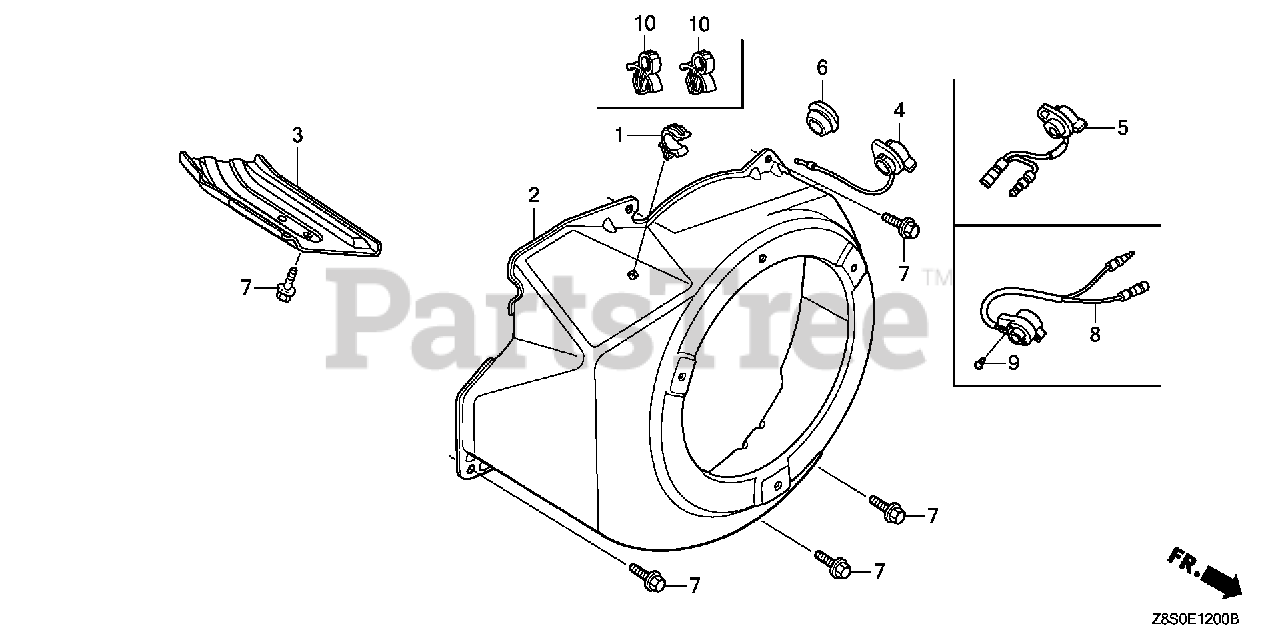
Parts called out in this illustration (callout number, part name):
1	CLIP, TUBE
2	COVER, FAN *NH1* (BLACK)
2	COVER, FAN *R280* (POWER RED)
7	BOLT, FLANGE (6X12) (CT200)
8	SWITCH ASSY., ENGINE STOP
9	SCREW, TAPPING (3X6) (PO)
